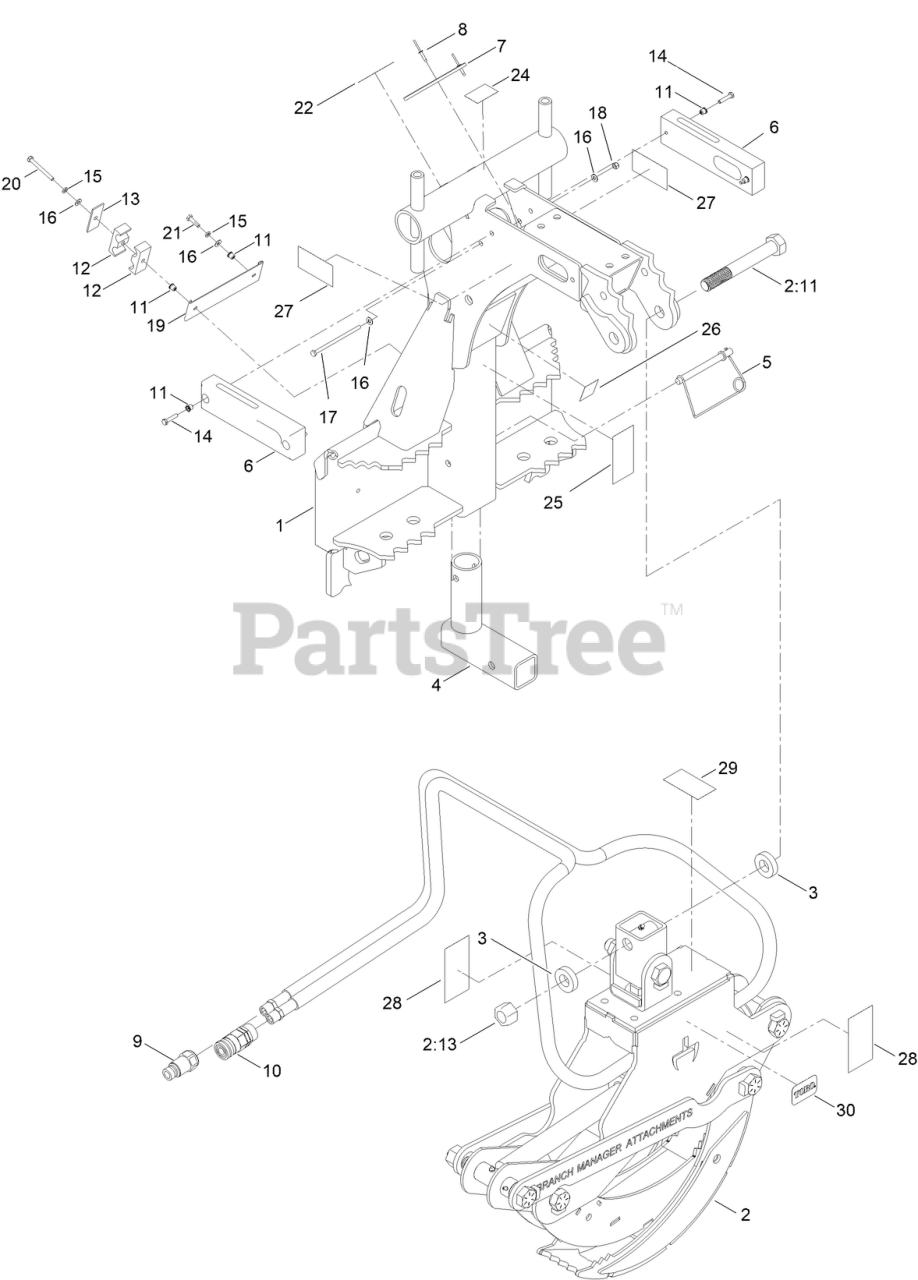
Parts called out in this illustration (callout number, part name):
1	FRAME-HANGER, LOG GRAPPLE
2	GRAPPLE HEAD
2:11	SCREW-HH
3	SPACER, HANGER
4	HITCH-RECEIVER
5	PIN-LYNCH
6	SCABBARD-SAW
7	PROTECTOR-HOSE, REAR
8	RIVET-POP
9	COUPLER-MALE, FLAT FACE
10	COUPLER-FEMALE, FLAT FACE
11	NUT-INSERT
12	CLAMP-HOSE, PLASTIC
13	TOP, HOSE CLAMP
14	SCREW-HH
15	WASHER-LOCK
16	WASHER-FLAT
17	SCREW-HH
18	NUT-LOCK, NI
19	BRACKET-HOSE MOUNT
20	SCREW-HH
21	SCREW-HH
22	DECAL-RATED CAPACITY
24	DECAL-BOLLARD CAPACITY
25	DECAL-COLLISION HAZARD
26	DECAL-HITCH CAPACITY
27	DECAL-CRUSHING WARNING
28	WARNING MOVING PARTS
29	DECAL-MOVING PARTS ISO
30	DECAL-LOGO
